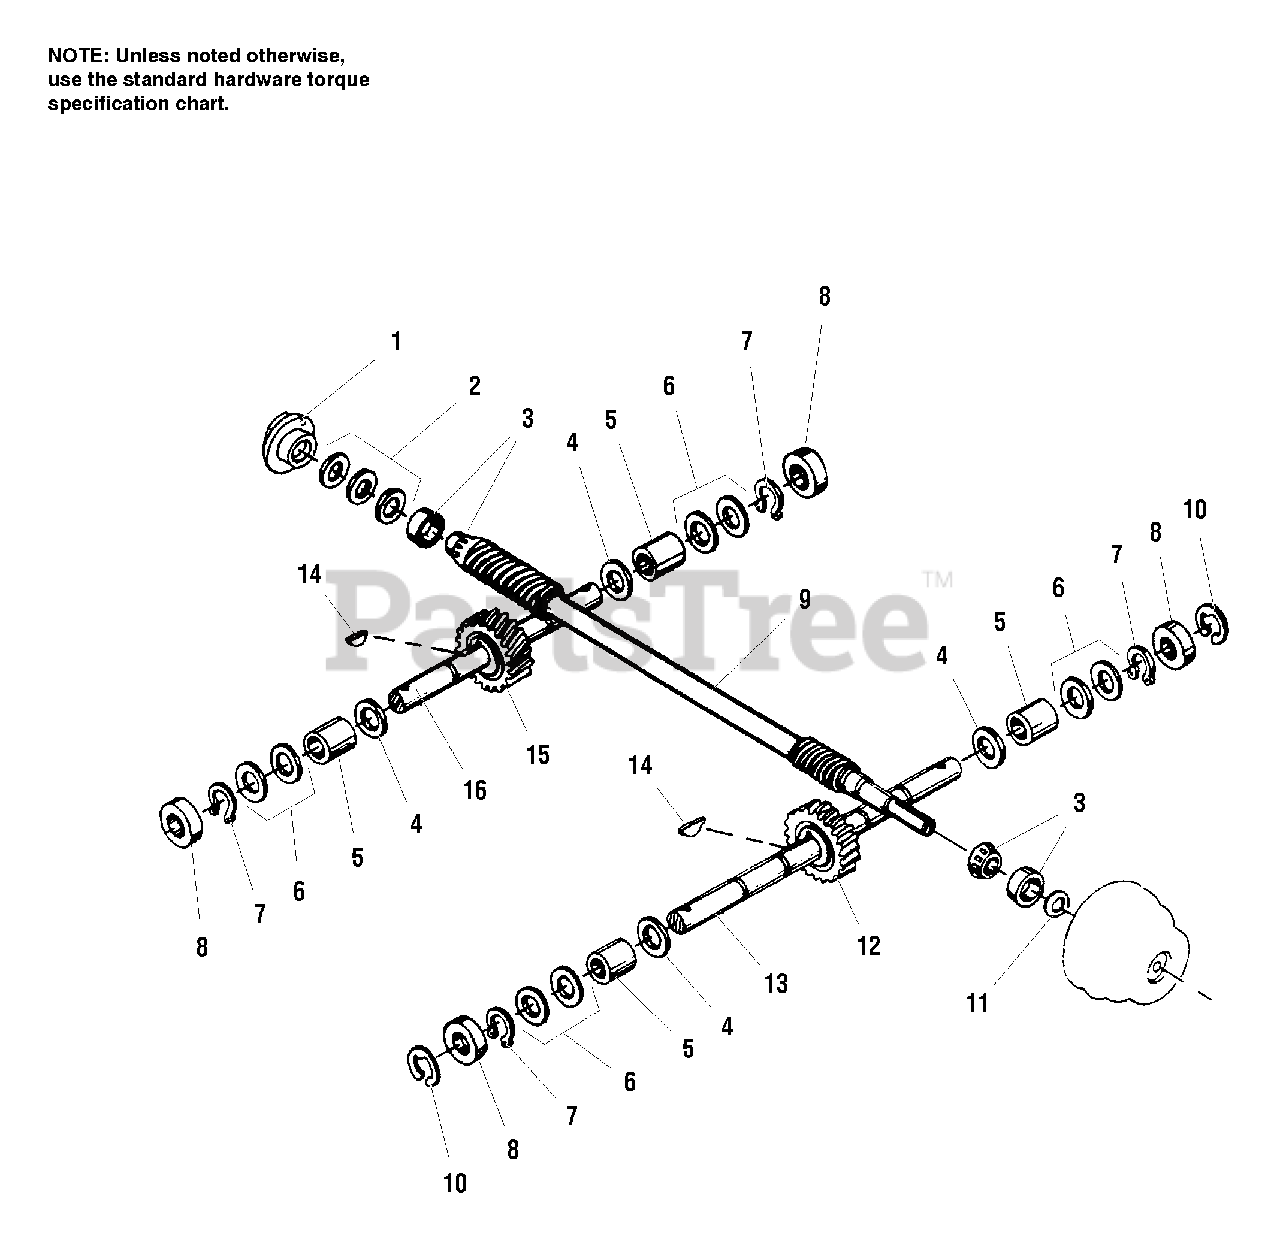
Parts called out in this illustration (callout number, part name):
1	CAP, Rear Bearing
2	SHIM SET, Rear Bearing Cap
2	SHIM, 1.750 OD x .062" thick
2	SHIM, 1.750 OD x .030" thick
2	SHIM, 1.750 OD x .015" thick
2	SHIM, 1.750 OD x .010" thick
3	BEARING, Tapered
4	SPACER, 1.250" x 1.000" x .062" thick
6	SHIM SET, Axle Spacer Kit
6	SHIM, 1.375 OD x .062" thick
6	SHIM, 1.375 OD x .030" thick
6	SHIM, 1.375 OD x .015" thick
6	SHIM, 1.375 OD x .010" thick
7	SNAP RING, Retainer, Internal
8	SEAL, Tiller Housing
9	MAIN DRIVE SHAFT
10	SNAP RING, Retainer, External
11	OIL SEAL, Drive Shaft
12	GEAR, Worm, Wheel Shaft
13	WHEEL SHAFT ASSEMBLY, Lockpin
13	WHEEL SHAFT ASSEMBLY, Lockout
14	KEY, 1/4" x 1"
15	GEAR, Worm, Tiller Shaft
16	TILLER SHAFT ASSEMBLY
